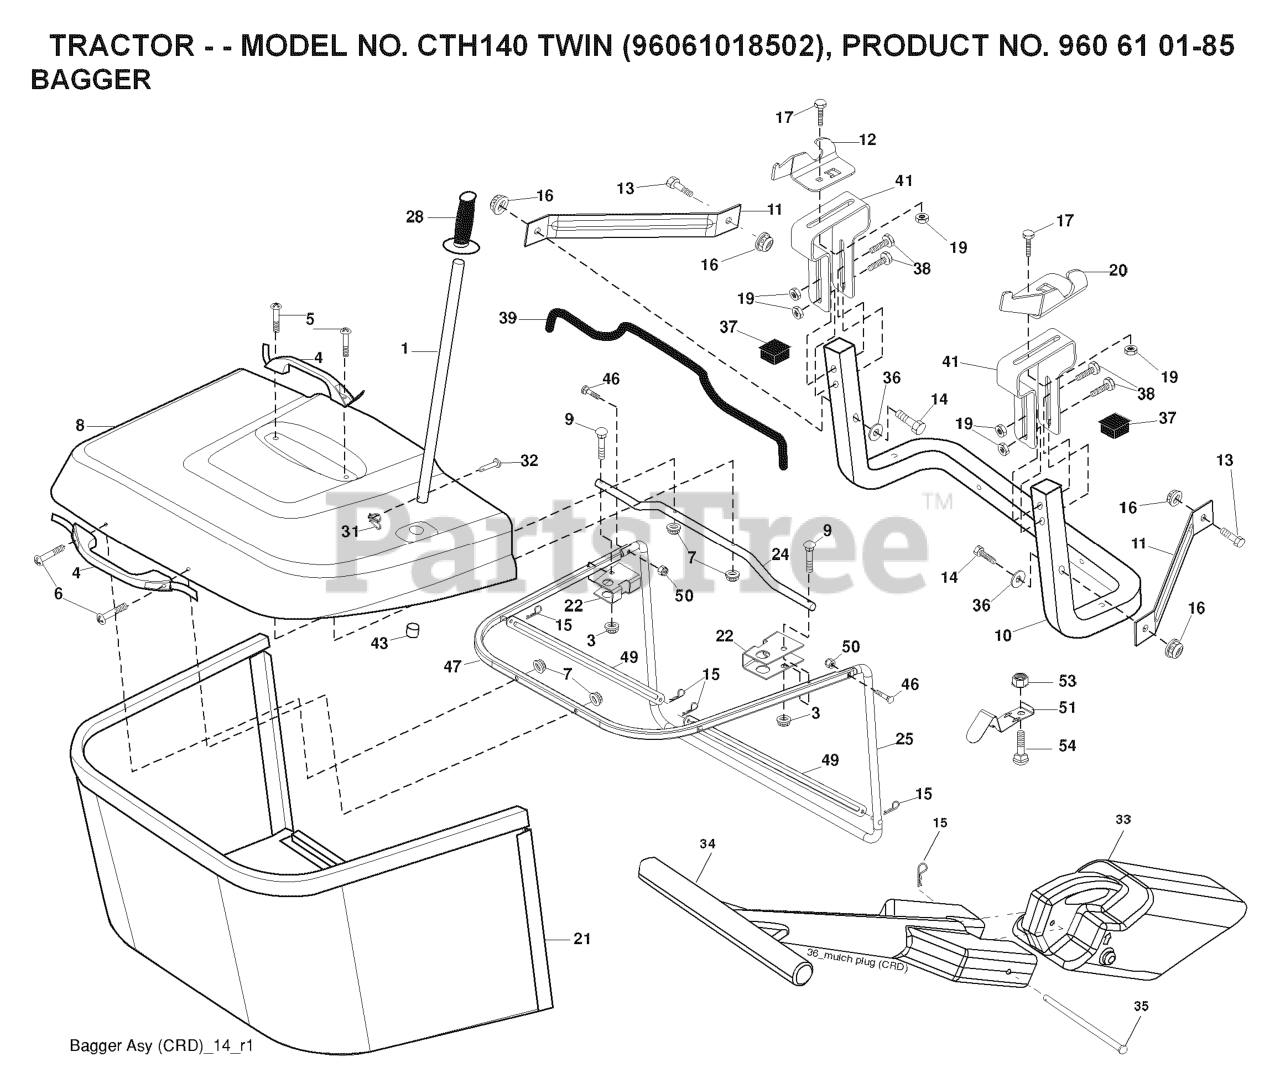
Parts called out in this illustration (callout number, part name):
1	TUBE HANDLE
3	NUT T
4	HANDLE.BAGGER.W/LVRS.BLK.CRD
5	SCREW.PAN.HEAD
6	REPL BY 532 75 00-29
8	COVER.PNT.BGR.CRD.WSLOTS.MS668
9	Bolt Carriage 1/4-20 x 2.25d x Gr.5
10	TUBE
11	BRACKET.SUPPORT.UPPER.BAG.CRD
12	BRKT PIVOT
14	BOLT-HEX EAK
15	RETAINER-SPRNG RB
16	NUT LOCK FLG 3/8-16 UNC
17	RP BOLT 5/16-18 X3/4 ZN/YEL GR
19	NUT LOCK HEX FLANGE 5/16-18
20	BRKT.PIVOT.RH.CRD
21	BAGGER.ASM.CRD.2007
22	BRKT.SIDE.BAG.CRD
24	TUBE.PIVOT.BAG.CRD.BLACK
25	PIPE
28	GRIP.HANDLE.BLACK
31	RETAINER CLIP
32	RIVET,DRILLED
33	PLUG.MULCHER.92 CRD
34	HANDLE.MULCHER.92.CRD (2 2)
36	WASHER
37	Plug Support Bagger CRD
38	BOLT.5/16-18X2.5
39	SEAL.TRIM.37'
41	BRKT.VERT.ADJ.BAGGER.CRD
43	PLUG, TUBING END
46	BOLT.CARRIAGE.5/16-18
47	PIPE
49	ROD
50	NUT.71038.31-18.HEX.NYLOCK
51	LATCH
53	NUT
54	BOLT
